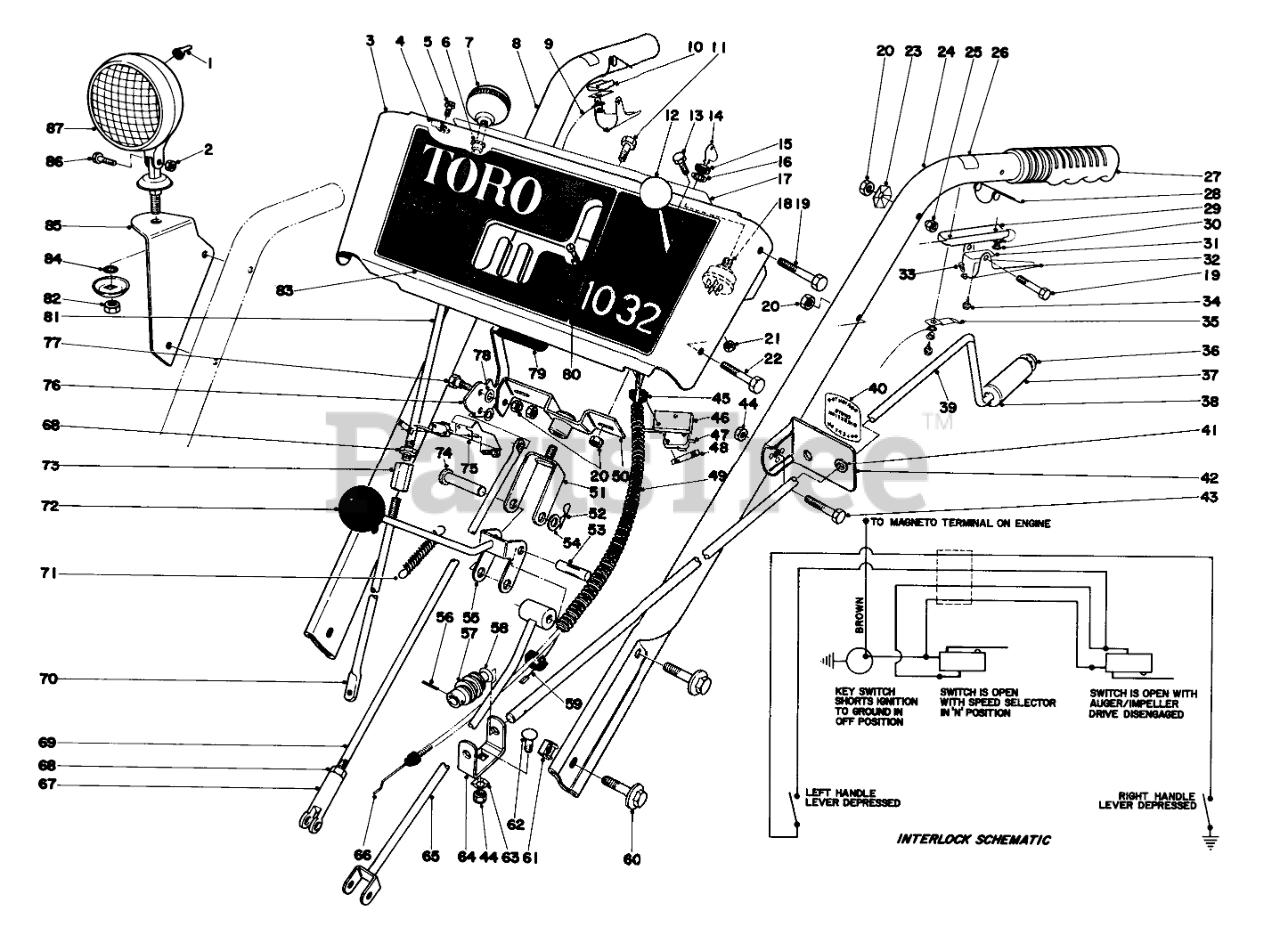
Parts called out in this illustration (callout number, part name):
1	Boot-Switch
3	Escutcheon Plate (Incl. Ref. #17 & 83)
4	PLASTIC CLIP
5	SCREW-HWHTF
6	Bushing
7	KNOB-LEVER
8	Handle Right
9	Wire Harness Interlock
10	Insulator
11	SCREW-HH
12	KNOB-CONTROL
13	HEX HEAD SEMS 10-24X1/2
14	Key
15	NUT-HH
16	WASHER-TOOTH, INTERNAL
17	Decal-Escutcheon Back
18	SWITCH-STARTER
19	SCREW-HH
20	NUT-LOCK, CONE
21	Nut
22	SCREW-HH
23	Washer
24	Handle Left
25	NUT-CAP
26	Decal Safety Interlock
27	Grip Handle
28	INTERLOCK SPRING
29	Insulator
30	WASHER INSULATOR
31	INTERLOCK CONTACT
32	Safety Lever
33	1/4 PLASTIC RIVET
34	Screw
35	CONTACT BRACKET
36	RETAINER-PUSH ON
37	CHUTE CONTROL GRIP
38	WASHER-FLAT
39	ROD CHUTE CONTROL
40	Decal Chute Direction
41	Bushing
42	Bracket-Chute Control Mounting (Incl. Ref. #40-41)
43	SCREW-HH
44	NUT-LOCK, CONE
46	SWITCH MTG PAD
47	MICRO SWITCH
48	NUT-SPEED
49	Cover Harness
50	SWIVEL BLOCK WA
51	Pivot Bracket
52	PIN-HAIR
53	3/8 X 1-1/4 ROL
54	WASHER-FLAT
55	Rod Shift
56	PIN-SPRING
57	GEAR-WORM, CHUTE
58	WASHER-SPRING
59	Ignition Wire Harness
60	SCREW-HHF
61	Retained Nut
62	SCREW-CARR
63	WASHER-LOCK
64	WORM BRACKET
65	Trunnion
66	Throttle Contrl
67	Clevis
68	NUT-HJ
69	DRAG LINK
70	LOWER WHL CLUTCH ROD
71	CONT ROD SPRING 0
73	WHL ROD COUPLING
74	PIN-CLEVIS
75	SWITCH BRKT
76	Auger Clutch Handle
77	SCREW-SHOULDER
78	WASHER-PLAIN
79	AUGER CLUTCH HND GRIP
80	SCREW-SPH
81	Rod Wheel Clutch
82	NUT-HEX
83	Decal-Escutcheon
84	WASHER-LOCK, INTERNAL
85	Lamp Mount
86	SCREW-HH
87	HEADLAMP ASM
